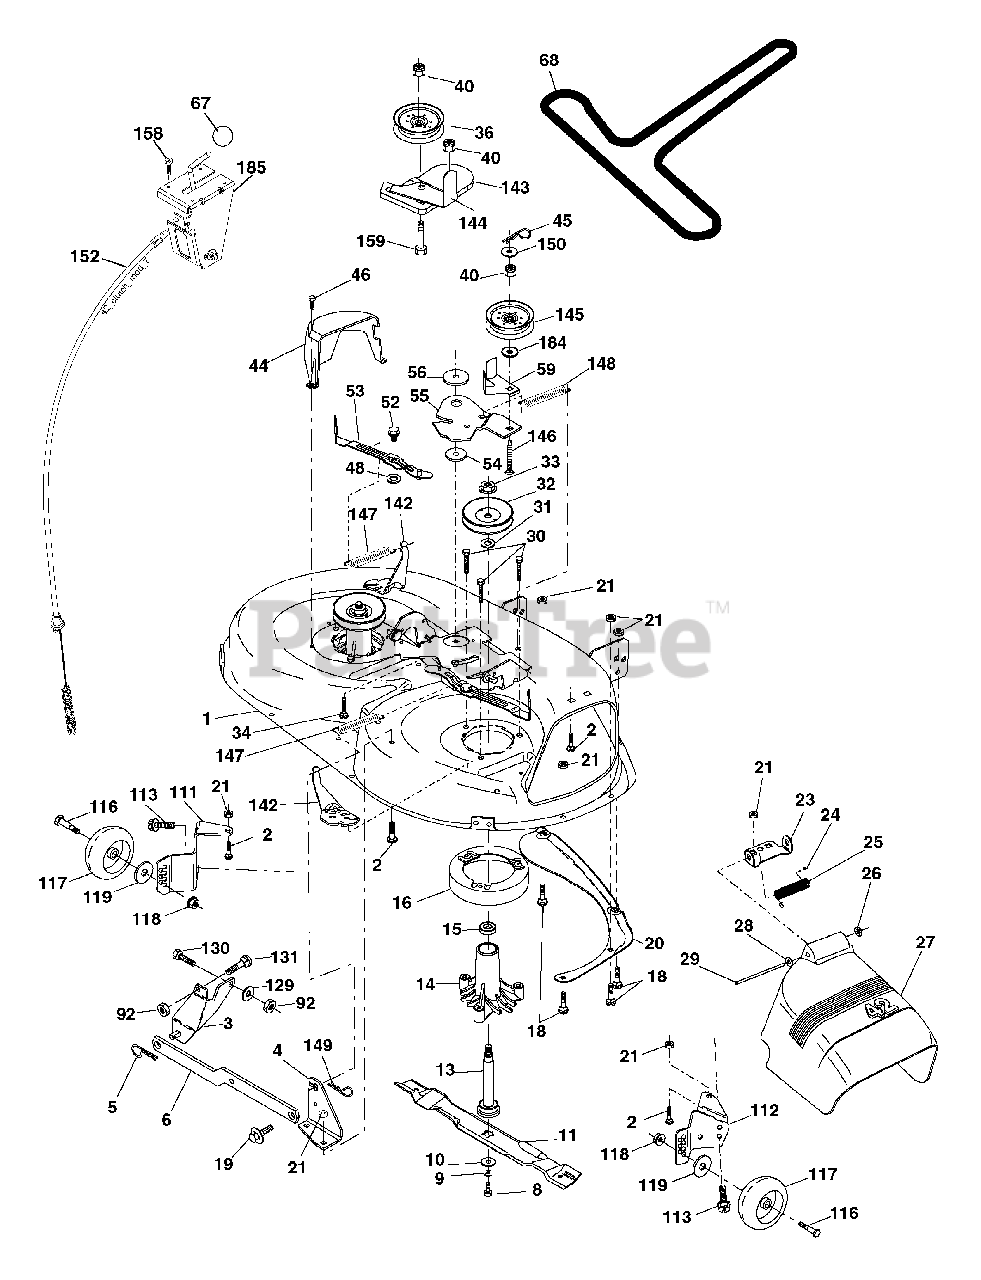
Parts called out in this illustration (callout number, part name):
1	Deck Asm MWR 42" weldment
2	Bolt Rdhd Sqnk 5/16-18 unc x 3/4
3	Bracket Asm Fr Sway Bar 38/42
4	Bracket Asm Deck 42" sway Bar
5	Retainer Spring
6	Deck Sway Bar
8	Bolt 3/8 - 24 x 1.25 Gr. 8
9	Washer Lock Hvy 3/8
10	Washer Hard Blade Mower Vented
11	Blade, 42" Hi-Lift
11	Blade Mower 42"
11	Blade, 42" Mulching Premium
13	Shaft Asm W/lower Bearing
14	Housing Mandrel Vented
15	Bearing Ball Mandrel
16	Stripper Mower
18	Bolt Rdhd Sqnk 5/16-18 x 5/8
19	Bolt Shoulder
20	Baffle Vortex 42
21	Nut Crownlock 5/16-18 unc
23	Bracket Deflector Mower 42"
24	Cap Sleeve 80 x 112 Blk Mower
25	Spring Torsion Deflector 2 52
26	Nut Push Phos & Oil
27	Shield Deflector Mower 42" Blk
28	Washer 11/32 x 5/8 x 16 Ga.
29	Rod Hinge 42" 6 75 Wlg
30	Screw Thd Rolling
31	Washer Spacer
32	Pulley Mandrel 42"
33	Nut Toplock Flng
34	Bolt Rdhd 3/8-16 unc x 1-1/2 Gr. 5
36	Pulley Idler Flat
40	Nut Lock 3/8-16 unc
44	Guard Mandrel LH Black
45	Spring Retainer 1" Zinc/cad
46	Screw Hex Thd Cut 1/4-20 x 5/8 T
48	Washer Hardened Smaller
52	Bolt Shoulder 5/16-18 unc Blkz
53	Arm Asm Pad Brake
54	Washer Hardened
55	Arm Idler 42" mower LT/YT
56	Spacer Retainer Mower
59	Guard TUV Idler
67	Knob Rd 3/8-16 Plstc Thds Blk
68	V-Belt Mower 42"
92	Nut 3/8-16 unc
111	Bracket Wheel Guage LH
112	Bracket Wheel Guage RH
113	Bolt 5/16-18 Hex Whs-Hd Lck Ser.
116	Bolt Shoulder
117	Wheel Guage
118	Nut Lock 3/8-16 unc
119	Washer 3/8 x 7/8 x 14 Ga.
129	Washer 13/32 x 13/16 x 12 Ga.
130	Bolt 3/8-16 x 1 Gr. 5
131	Bolt 3/8-16 x 1
142	Arm Spring Brake Mower
143	Bracket Arm Idler 42"
144	Keeper Belt 42" Clutch
145	Pulley Idler Flat
146	Bolt Carriage Idler
147	Spring Extension
148	Spring Return Idler
149	Retainer Spring Yellow
150	Washer 9/32 x 3/4 x 10 Ga.
152	Clutch Cable 42"
158	Screw Hex Thd Cut 1/4-20 x 1/2
159	Bolt Rdhd Sqn 3/8-16 unc x 1-3/4
184	Washer 13/32 x 7/8 x 10 Ga.
185	Head Asm. Cable Clutch
